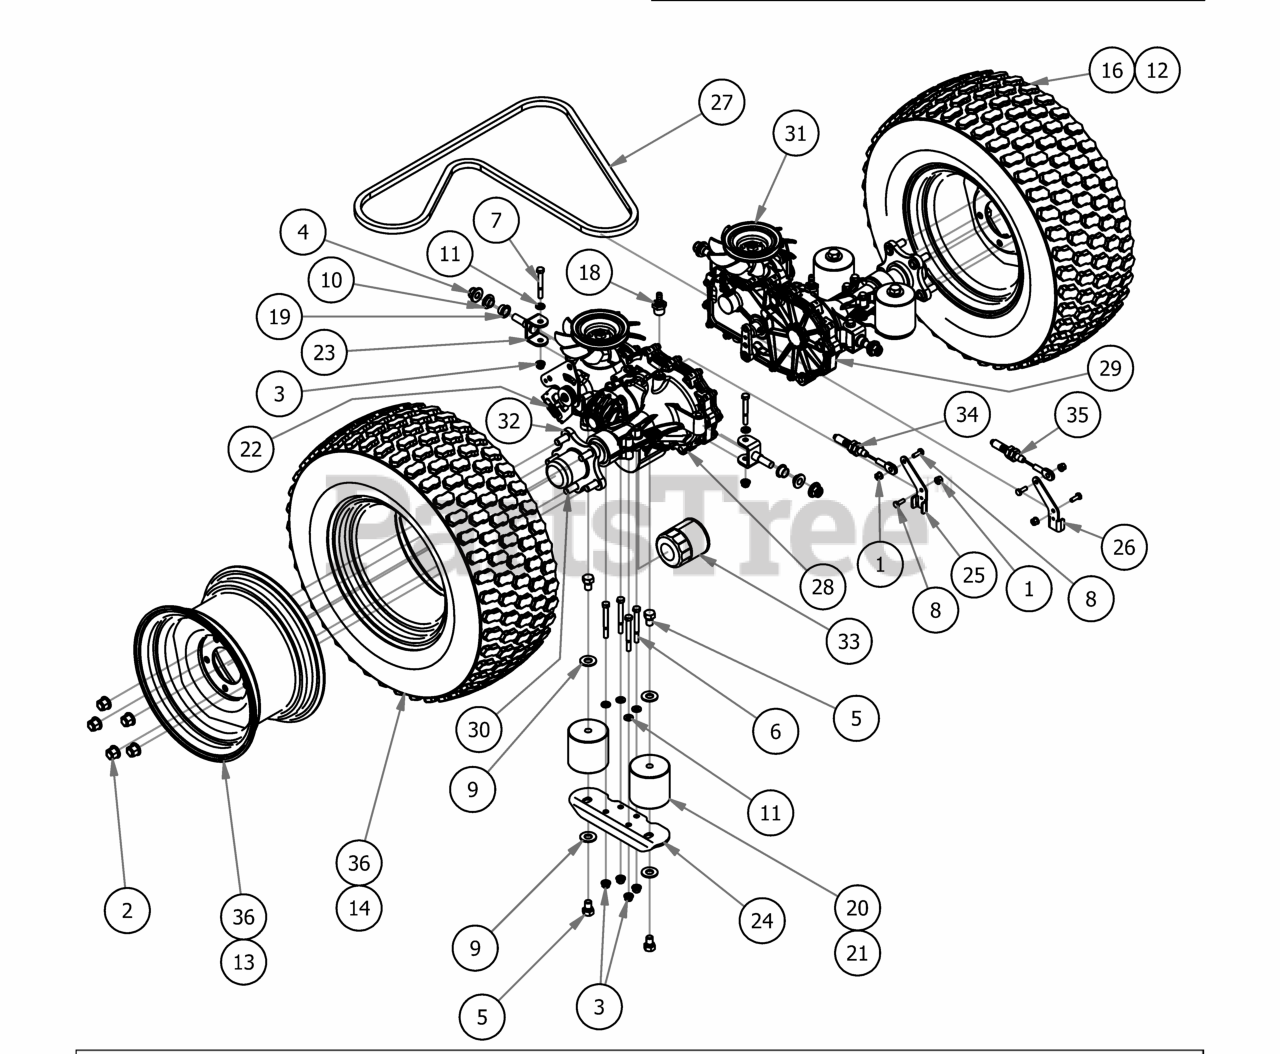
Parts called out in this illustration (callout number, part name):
1	1/4-20 Nylon Insert flange Nut
2	Acorn Lug Nut
3	5/16" Nylon Flange Nut
4	1/2-13 Nylon Flange Nut
5	1/2" x 3/4" Hex Bolt
6	5/16" x 3" Hex Bolt
7	5/16" x 2 1/2" Bolt
8	1/4" x 3/4" Hex Bolt
9	1/2" Washer (Grade 8)
10	.515 ID Nylon Shoulder Washer
11	5/16" Flat Washer
12	Tire and Wheel Assembly (28 and 29) (48" Maverick Only)
13	12 x 7" Black Wheel (48" Maverick Only)
14	23 x 8.50 - 12 Tire (48" Maverick Only)
16	2019 Maverick Reaper Turf Tire and Wheel Assembly
18	45 degree fitting
19	Bronze Bushing - SF - 2024-8
20	Vibration Mount-Green Dot
21	Vibration Mount-Red Dot (48" Maverick Only)
22	Gold Transaxle Spring
23	Maverick Rear Transaxle Pivot Bracket
24	Rear Susp Transaxle Mount
25	Brake Arm Ext (Left)
26	Brake Arm Ext (Right)
27	75.8" Pump Belt
28	3200 Left transaxle
29	3200 right transaxle
30	Transaxle Wheel Stud
31	Fan/Pully Kit for ZT and Maverick
32	Transaxle Hub
34	Brake Cable,18.5"
35	Brake Cable, 24.5"
36	23" x 10.50" X 12" Black Wheel Assembly
